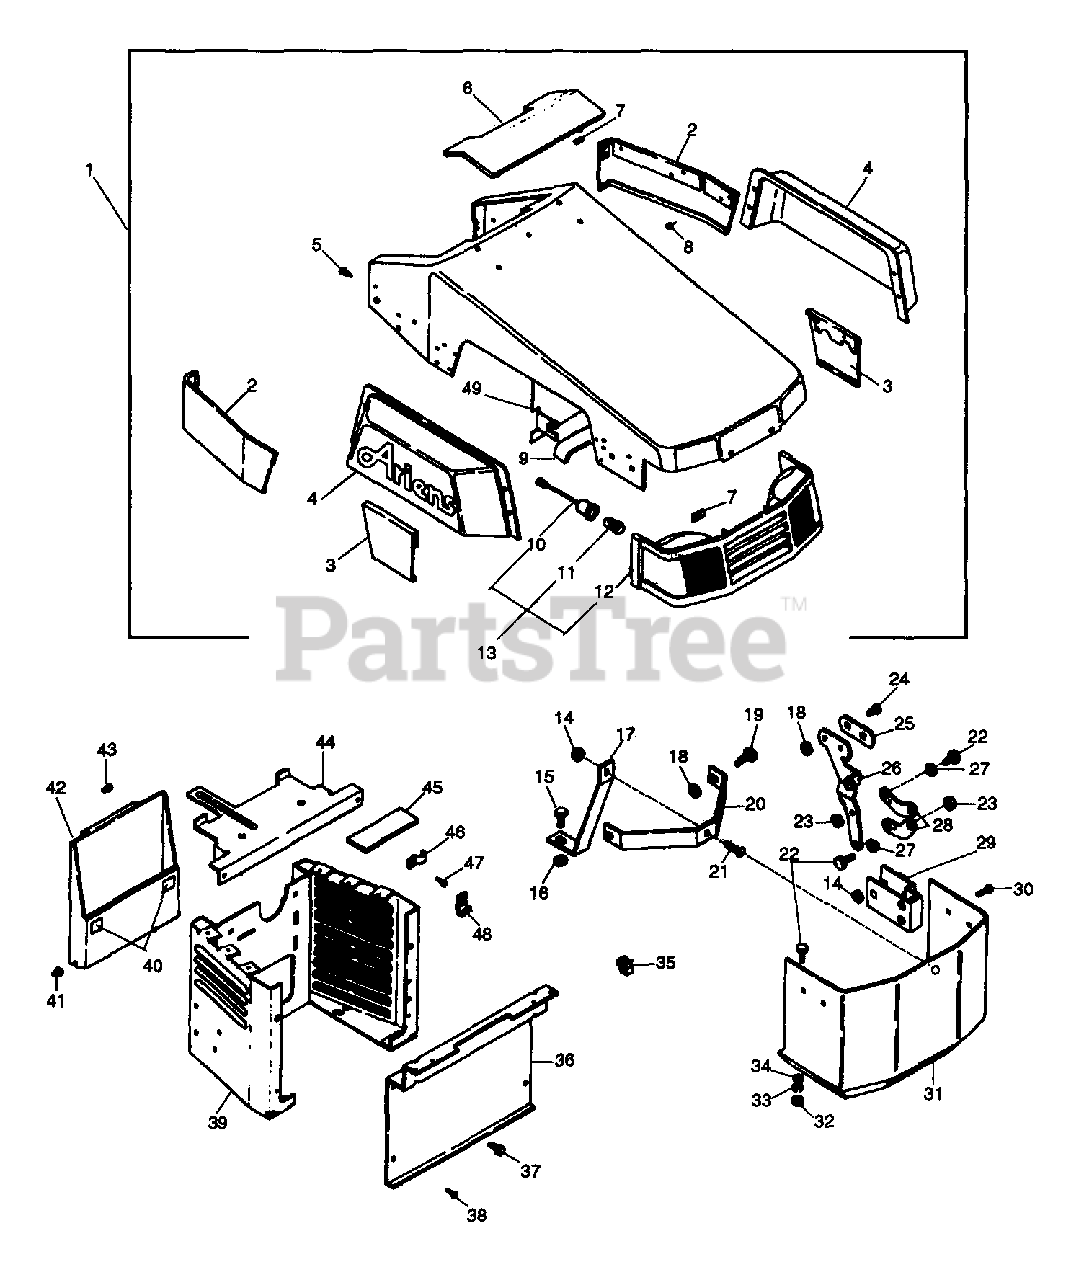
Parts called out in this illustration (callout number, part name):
1	HOOD ASSEMBLY
1	HOOD ASSEMBLY 14TW
1	HOOD ASSEMBLY 14S
2	REAR HOOD MOLDING R H
2	REAR HOOD MOLDING L H
3	FRONT HOOD MOLDING R H
3	FRONT HOOD MOLDING L H
3	L H FRONT MOLDING
4	ENGINE SHROUD
4	ENGINE SHROUD LH
6	HAND HOLD TRIM
7	NUT-SELF-THRDNG FITS.25 STUDPL
8	RVT-BRIV .153 X .179 DOME AL
9	FOAM TAPE
10	SOCKET & HARNESS
11	HEADLIGHT BULB, 1156
12	GRILL & LENS ASSEMBLY
13	HEAD LIGHT SYSTEM
14	NUT-LK-FLG .250-20 PL
15	BLT-RDHDSQNK .375-16X.75 GR5PL
16	NUT-LK-FLG .375-16 PL
18	NUT-FLG. .312-18 PL
19	BLT-RDHDSQNK .312-18X.62SHTPL
20	BRACE
21	BLT-RDHDSQNK .25-20X.75 GR5PL
22	BLT-HEX .31-18X.75 PL GR2
23	NUT-LK .312-18 GR A PL
24	BLT-RDHDSQNK .31-18X.75 GR5 PL
25	SPACER STRAP
26	HINGE ARM R H
26	HINGE ARM L H
26	ARM L H
26	ARM R H
27	BSHG, FLG .325X.499X.26X.88
29	HINGE BRACKET
30	BLT-RDHDSQNK .25-20X.50 SHT PL
31	GRILL
31	GRILL 14T
32	NUT-HEX .312-18
33	WSHR-LK .312X.097 PL HVY
34	WSHR-FL-STL .323X.625X.062 PL
35	CLIP-HARNESS TINNERMAN
36	BULKHEAD
37	SCR-TAP .312-18X.50 HWH PL TR
38	SCR-TAP 10-16X.50 HWH PL AB
39	DASH TOWER
40	CATCH ASSEMBLY
41	PLASTIC GROMMET
42	NOTE BOX
43	SCR-TAP 10-12X.50 CRPH PL A
44	BATTERY SUPPORT
45	FOAM TAPE
47	SCR-TAP 6-20X.50 CR 1A
49	HOOD BAFFLE 14 HP
